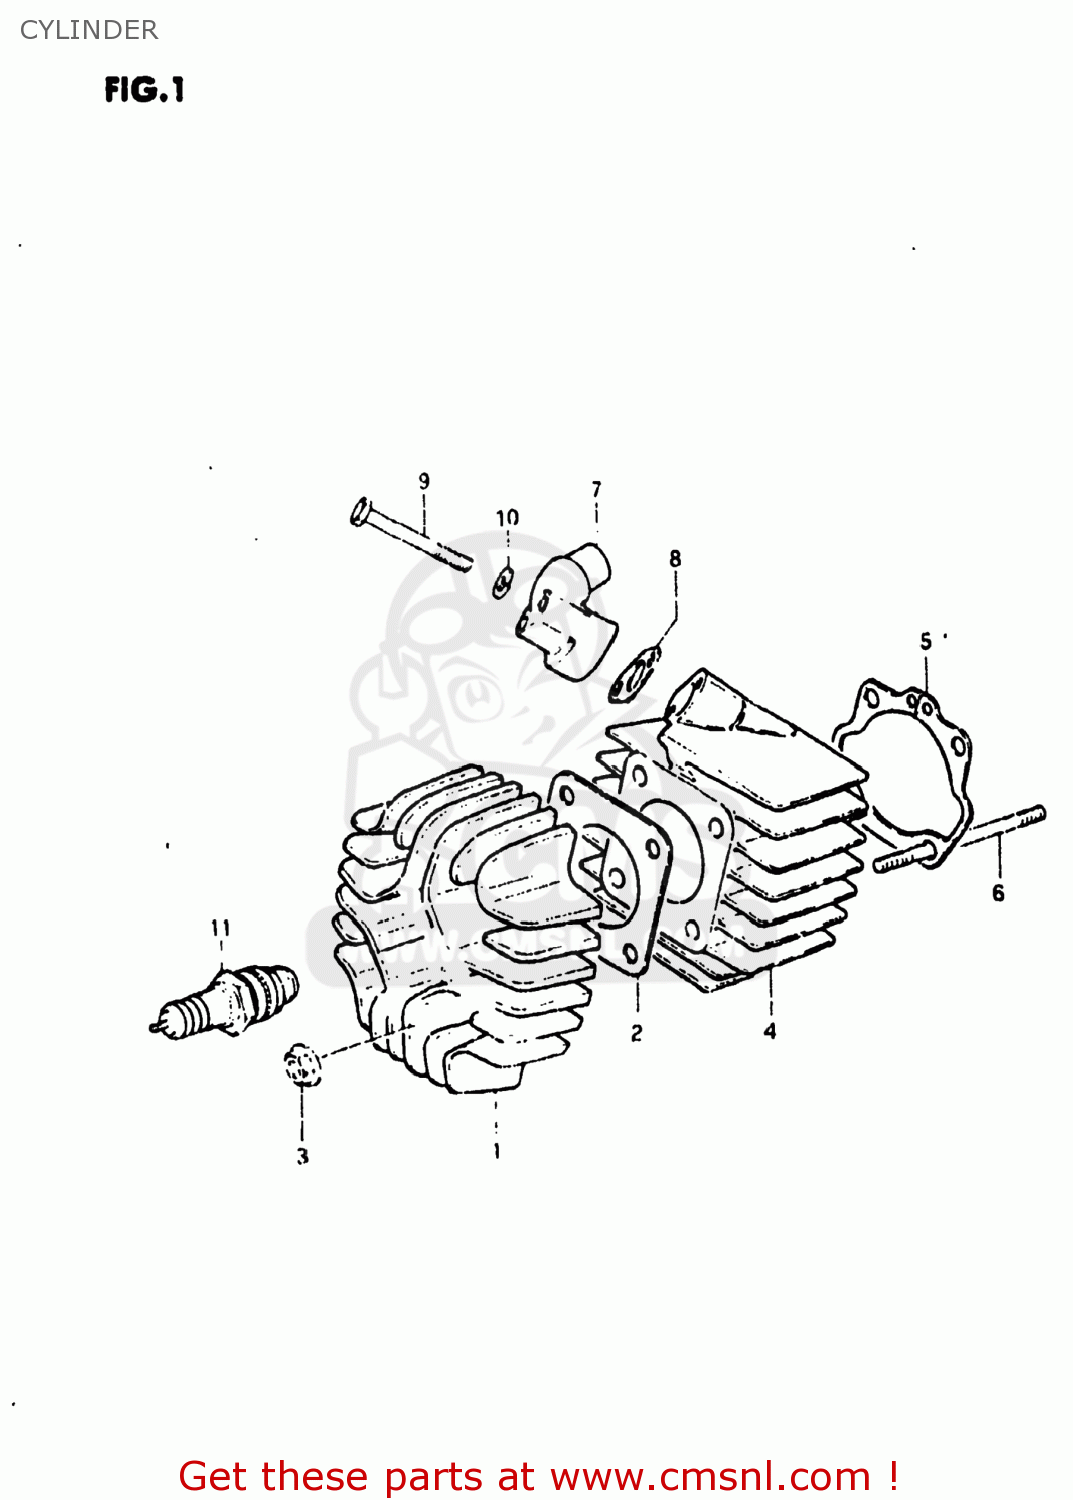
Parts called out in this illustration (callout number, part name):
1	HEAD,CYLINDER
2	GASKET,CYLINDER HEAD (NAS)
3	NUT
4	CYLINDER
5	GASKET,CYLINDER (MCA)
6	STUD BOLT
7	PIPE,INTAKE
8	GASKET (NAS)
9	BOLT
10	LOCK WASHER
11	SPARK PLUG
